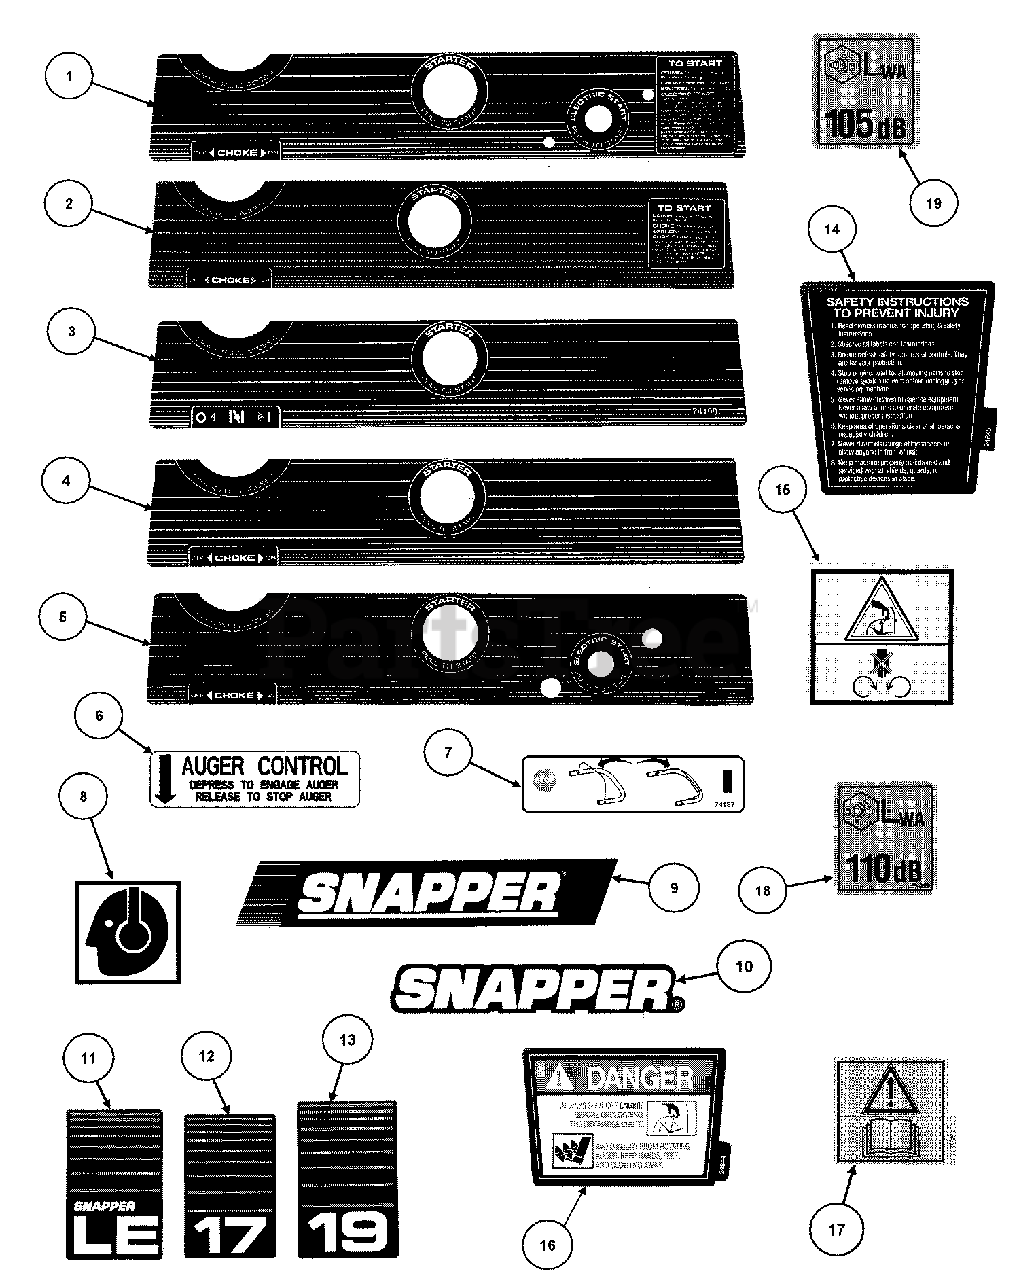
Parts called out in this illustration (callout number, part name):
1	DECAL, Panel Instructions
2	DECAL, Panel Instructions
3	DECAL, Panel Instructions
4	DECAL, Panel Instructions
5	DECAL, Panel Instructions
6	DECAL, Auger Control
7	DECAL, Auger Control
8	DECAL, Ear Protection
9	DECAL, SNAPPER (Belt Cover)
10	LOGO, SNAPPER
11	DECAL, L.E. Model
12	DECAL, 17" Model
13	DECAL, 19" Model
14	DECAL, Chute, Safety Instructions
15	DECAL, Chute
16	DECAL, Danger, Chute Deflector
17	DECAL, Deflector, Read Manual
18	DECAL, Sound (110 dB)
19	DECAL, Sound (105 dB)
